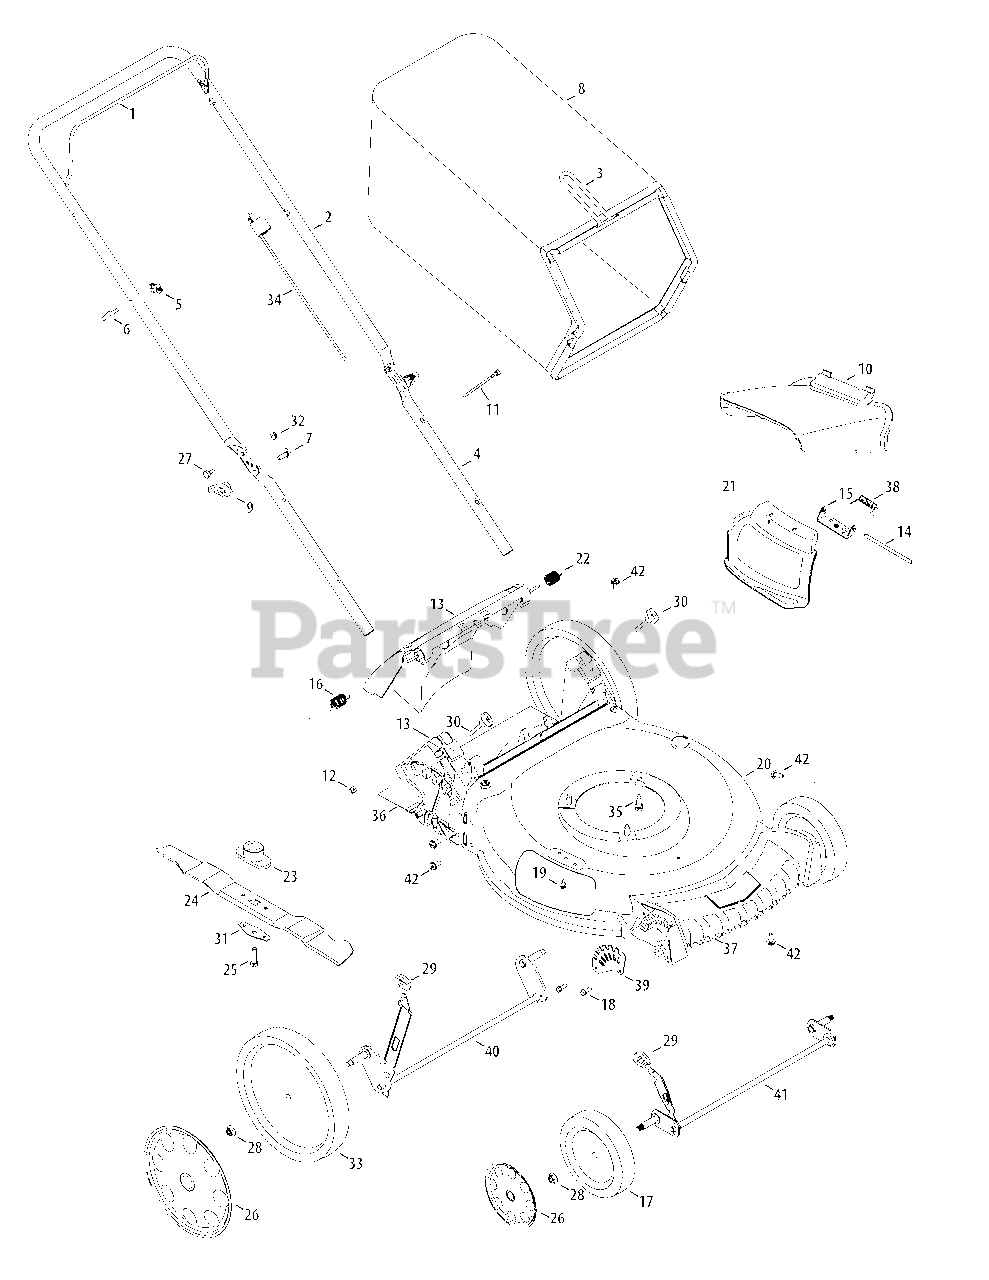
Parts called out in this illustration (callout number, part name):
1	Blade Control
2	Upper Handle
4	Lower Handle
6	Rope Guide
7	Carriage Screw ,5/16-18
8	Grass Bag
10	Side Chute
11	Cable Tie
12	Nut, Sq., 1/4-20
13	Rear Discharge Door Assembly
15	Chute Deflector Bracket
16	Torsion Spring - RH
17	Front Wheel
18	Screw, 1/4-15 x .750
19	Screw, 1/4-20 x .500
20	Deck , 21"
21	Hinged Mulch Plug Assembly
22	Torsion Spring - LH
23	Blade Adapter
24	Mulching Blade
25	Screw , 3/8-24 x 1.50
26	Hub Cap - Front
26	Hub Cap - Rear
27	Sldr. Screw, .375 x .126 x 1/4-20
28	Flange Lock Nut, 3/8-16
29	Adjustment Lever Knob
30	Wing Nut
31	Blade Bell Support
32	Nut, Flange Lock, 1/4-20
33	Rear Wheel
34	Control Cable
35	TT Sems Screw, 3/8-16 x 1.0
36	Trail shield
37	Front Cover
38	Torsion Spring
39	Front Height Adjuster Plate
40	Rear Axle Assembly
41	Front Axle Assembly
42	Screw, 5/16-14 x .750
